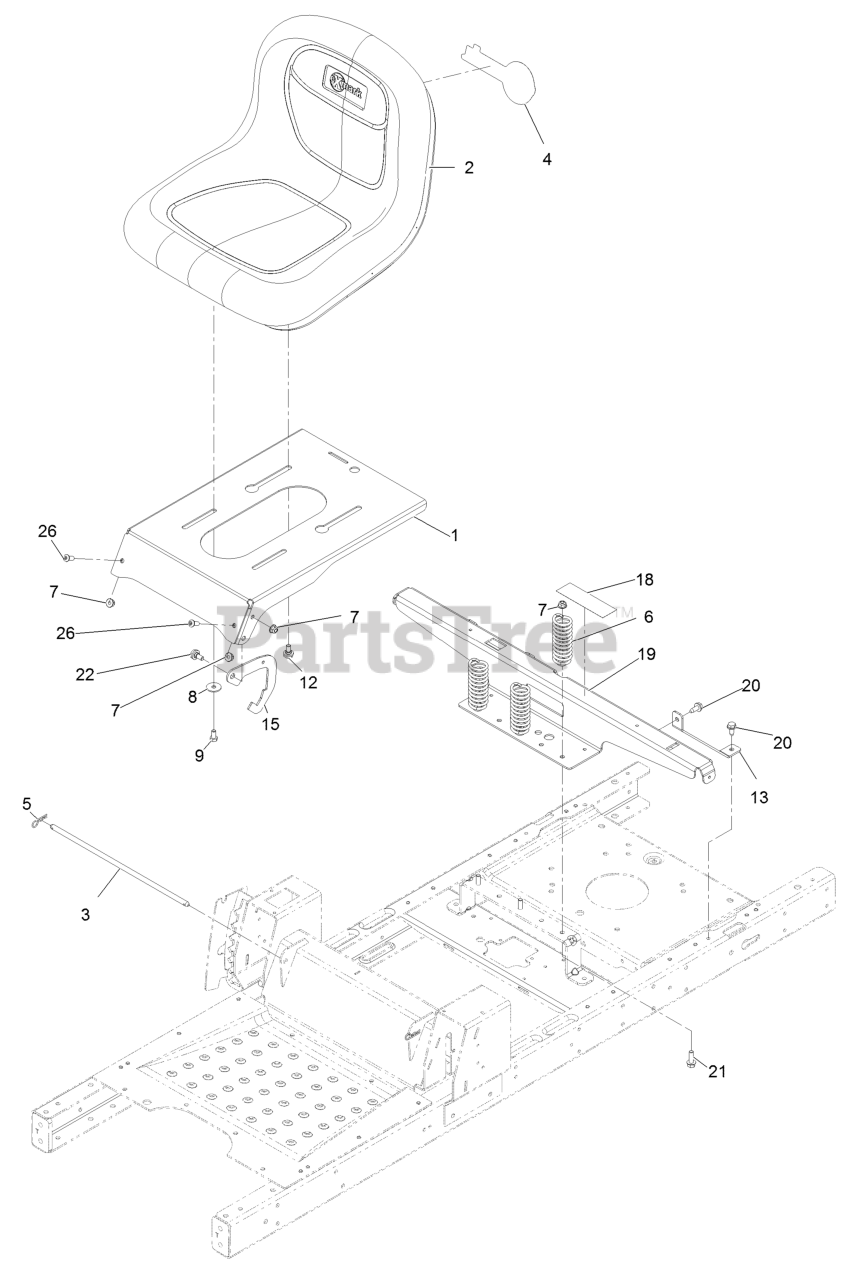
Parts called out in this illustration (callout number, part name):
2	SEAT-15 IN
3	ROD-PIVOT, NARROW
4	DECAL-EXMARK LOGO
5	PIN-COTTER
6	SPRING-COMPRESSION
7	NUT-HF, NI
8	WASHER-PIVOT
9	SCREW-HH
12	BOLT-SHOULDER,HFH
13	SUPPORT-TANK, REAR
15	LATCH-SEAT
18	DECAL-SERVICE, CE
19	SUPPORT-POD
20	Screw-HWH 5/16-18 X 3/4 Tf
21	SCREW-HHF
22	BOLT-SHOULDER,HFH
26	SCREW-HSBH
